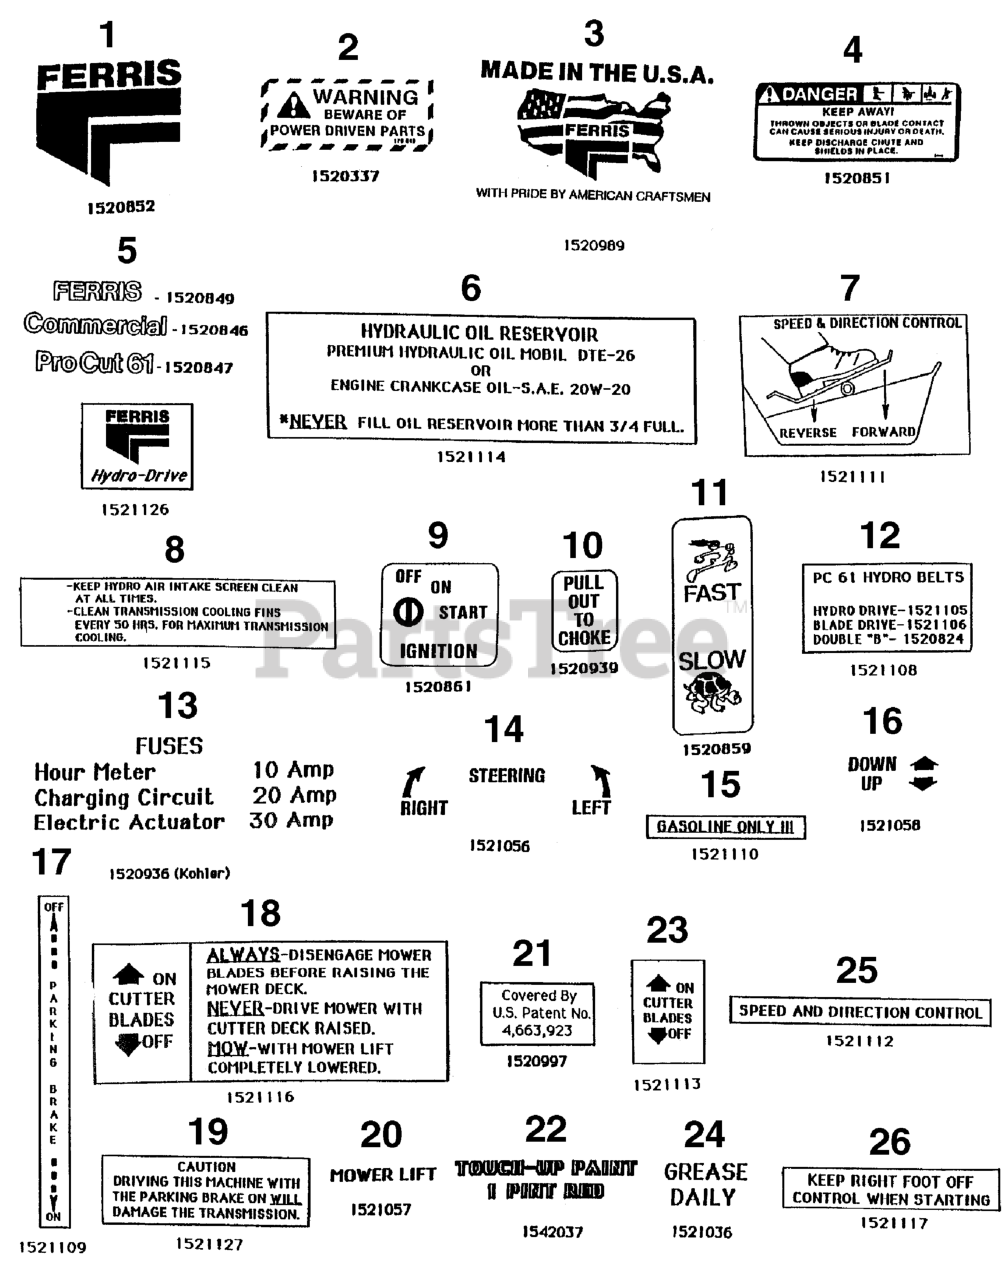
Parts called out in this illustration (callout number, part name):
1	DECAL, Ferris Logo, 10-3/4"
2	DECAL, Warning
3	DECAL, Made In The USA
4	DECAL, DANGER DO NOT OPERATE W/O DEFLECT
5	DECAL, FERRIS TEXT & LOGO
5	DECAL, Commercial
5	DECAL, Word, PROCUT 61
5	DECAL, Hydro Drive
6	DECAL, Reservior Hydraulic Oil
7	DECAL, Speed Control
8	DECAL, Hydro Screen
9	DECAL, Ignition
11	DECAL, Engine Speed
12	DECAL, Belt & Blade
13	DECAL, Fuses
14	DECAL, Steering Controls
15	DECAL, Gasoline Only
16	DECAL, Up / Down
17	DECAL, PARKING BRAKE-RIDER
18	DECAL, Cutter Blade Direction
19	DECAL, CAUTION Transmission Damage
20	DECAL, Mower Lift
21	DECAL, Patent
22	DECAL, Touch-Up Paint
23	DECAL, PTO Switch
24	DECAL, Grease Daily
26	DECAL, Right Foot Control
